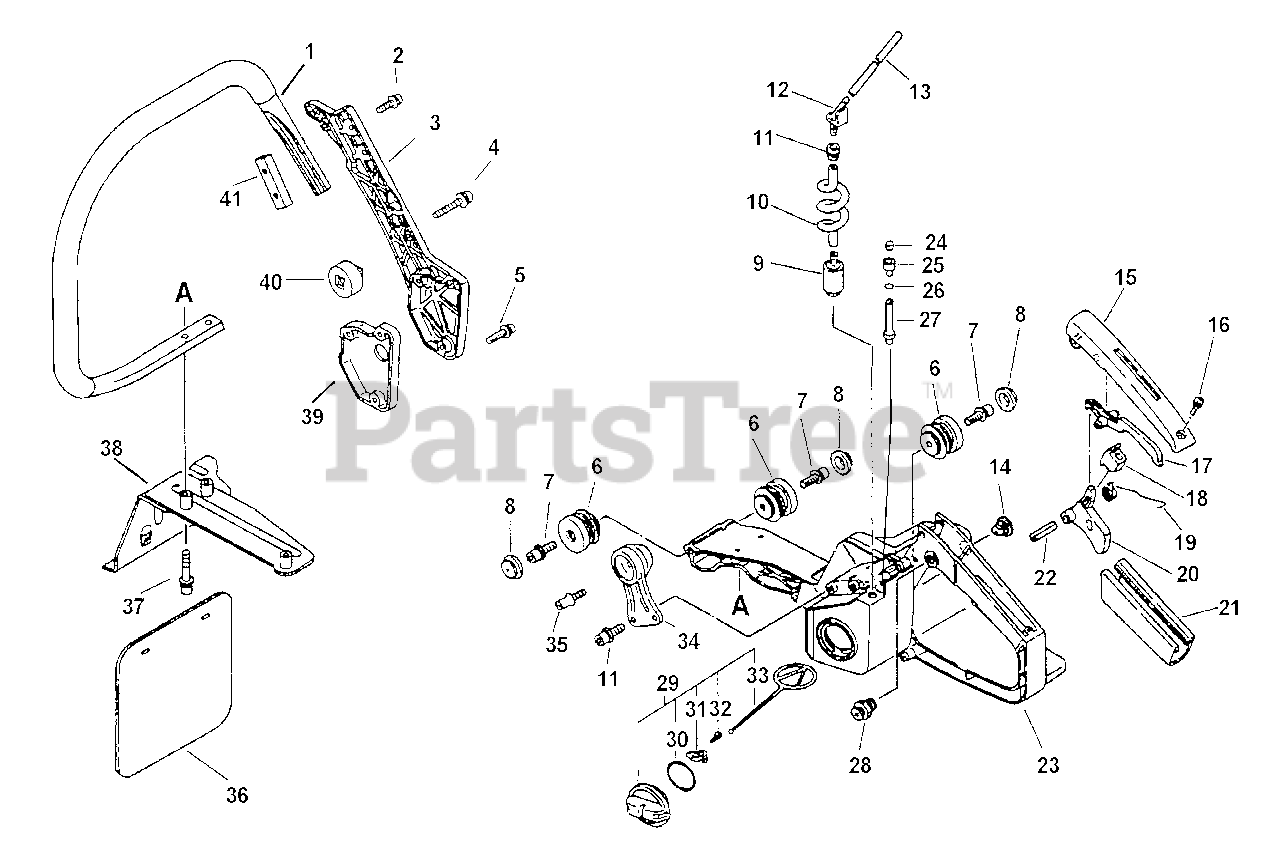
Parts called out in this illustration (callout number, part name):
1	HANDLE - FRONT
2	SCREW - 5X20
3	BRACKET, HANDLE - OUTER
4	SCREW - 5X30
5	SCREW - 5X35
7	SCREW - 5X14
8	CAP, CUSHION
9	FILTER, FUEL
10	PIPE - BLACK
11	GROMMET
12	CONNECTOR, PIPE
13	PIPE - 3X6X100 -- BLACK
15	COVER, HANDLE
16	SCREW - 4X14
17	LEVER, TRIGGER LOCKOUT
19	SPRING, TRIGGER
20	TRIGGER, THROTTLE
21	GRIP, HANDLE
22	PIN - SPRING -- 5X25
23	HANDLE - REAR
24	VENT, FUEL TANK
25	COVER, VENT
26	CLIP - 5.5
27	PIPE - VENT
28	LATCH, THROTTLE
29	CAP ASSY
30	O-RING - 29
31	RETAINER
32	SCREW - 3X8
33	CONNECTOR, CAP
36	SHIELD
37	SCREW - 5X30
38	FIXTURE, HANDLE
39	SPACER
